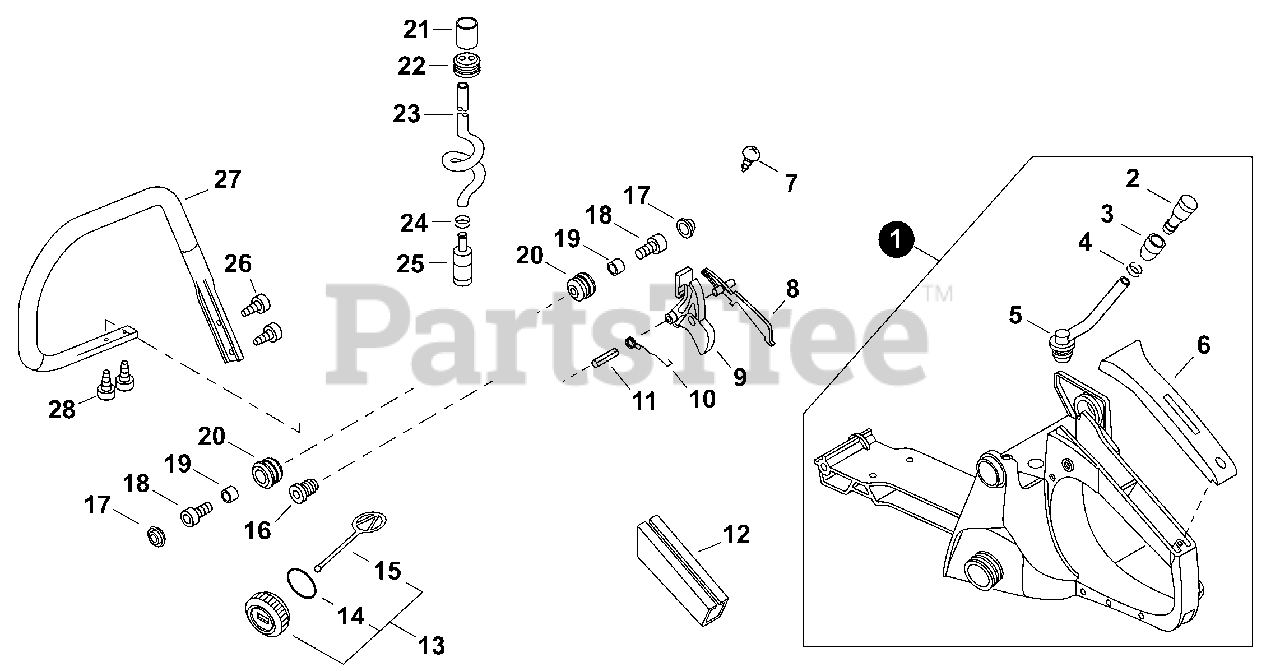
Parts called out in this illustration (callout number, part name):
1	HANDLE ASSY, REAR
2	VENT ASSY
3	HOLDER, VENT
4	CLIP Ø6.5 MM
5	PIPE, VENT 3×6×65
6	COVER, HANDLE
7	SCREW 4×14
8	LOCKOUT, THROTTLE
9	TRIGGER, THROTTLE
10	SPRING, TORSION
11	PIN, SPRING 4×30
12	GRIP, HANDLE
13	CAP ASSY, FUEL
14	O-RING 22
15	CONNECTOR, CAP L= 60 MM
17	CAP, CUSHION
18	BOLT, HEX 4×20
19	COLLAR 4.2×7×9.5
20	CUSHION 4
21	TUBE 8×9×16
22	GROMMET, FUEL
23	PIPE, FUEL 3×5×250
24	CLIP Ø6
25	FILTER, FUEL
26	SCREW TAPPING 5×20
27	HANDLE, FRONT - ALUMINUM
28	SCREW TAPPING 5×16
